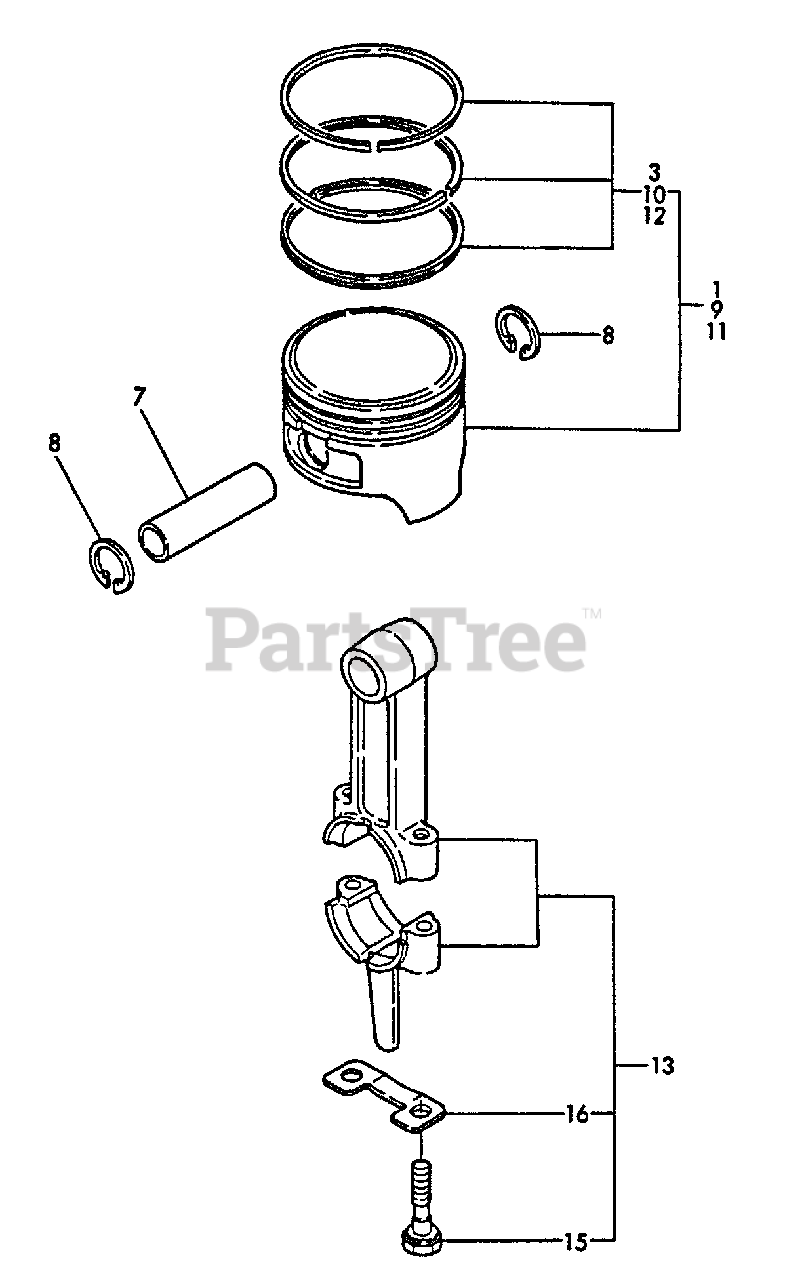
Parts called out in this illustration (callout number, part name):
1	PISTON ASSY
3	PISTON RING ASSY
7	PIN, PISTON
8	RING, RETAINING - 16
9	PISTON ASSY O.S.=0.25
10	RING ASSY O.S.=0.25
11	PISTON ASSY O.S.=0.5
12	RING ASSY O.S.=0.5
13	CONNECTING ROD ASSY
15	BOLT, ROD
16	WASHER
